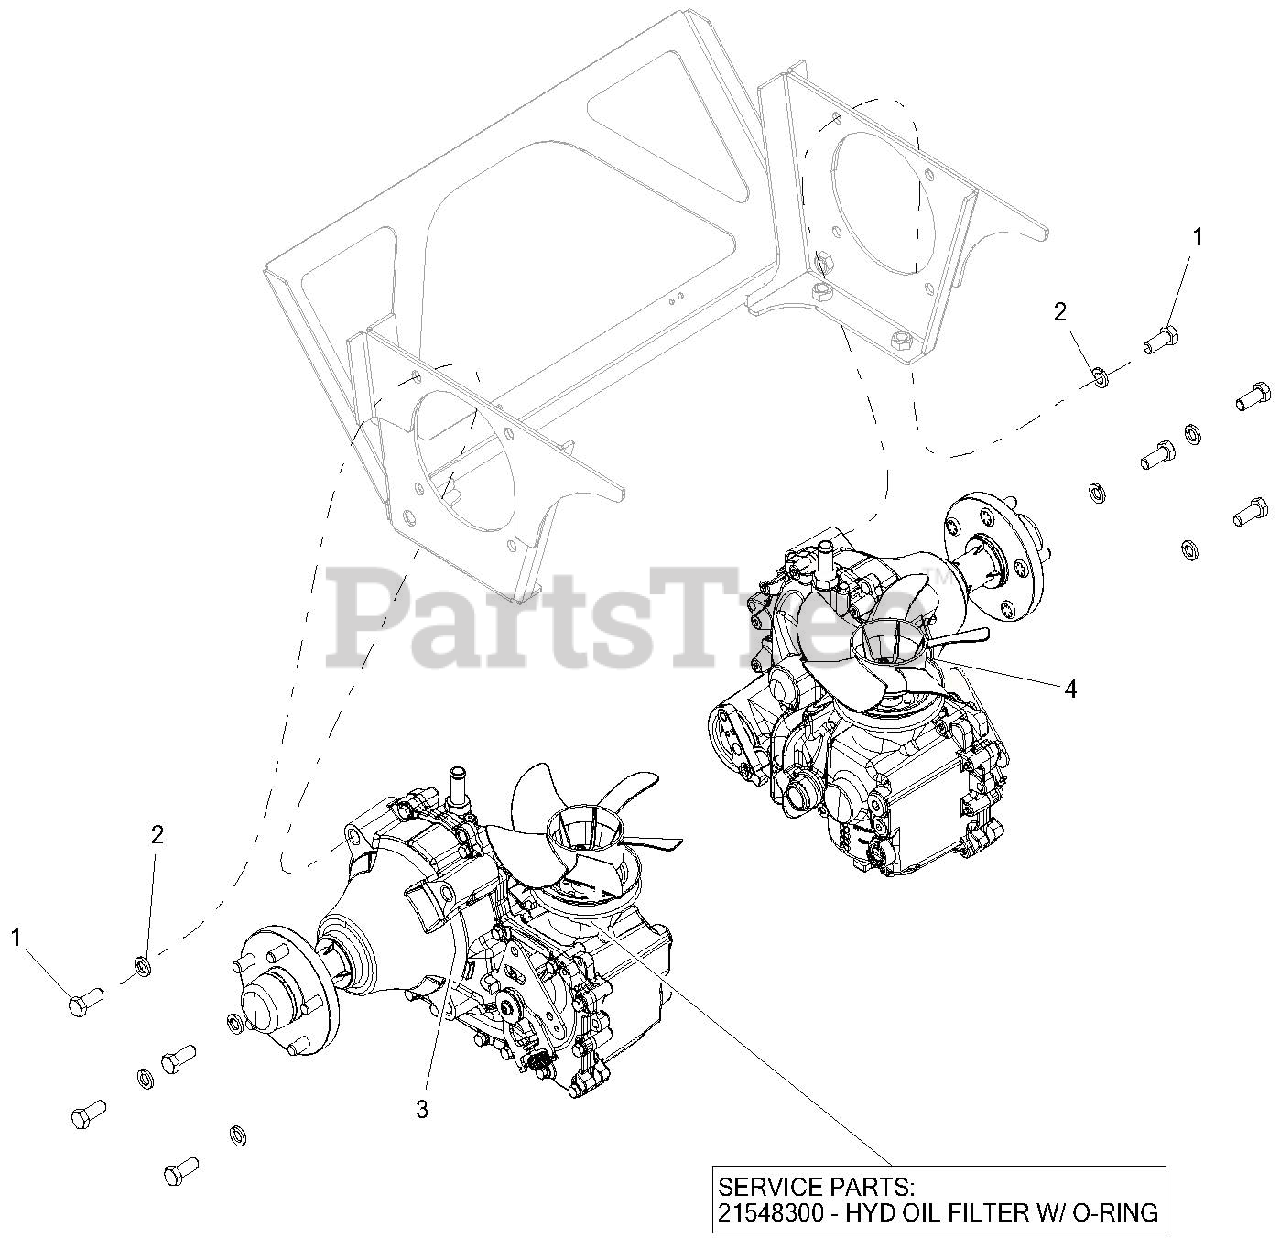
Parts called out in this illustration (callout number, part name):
1	BLT-HEX .50-13X1.25 GR5 YWZC
2	WSHR-LK .50X.125 REG YWZC
3	TRANS, R.H. HG ZT-5400
3	HYDRO OIL FILTER W/ O-RING
4	TRANS, LH HG ZT-5400
